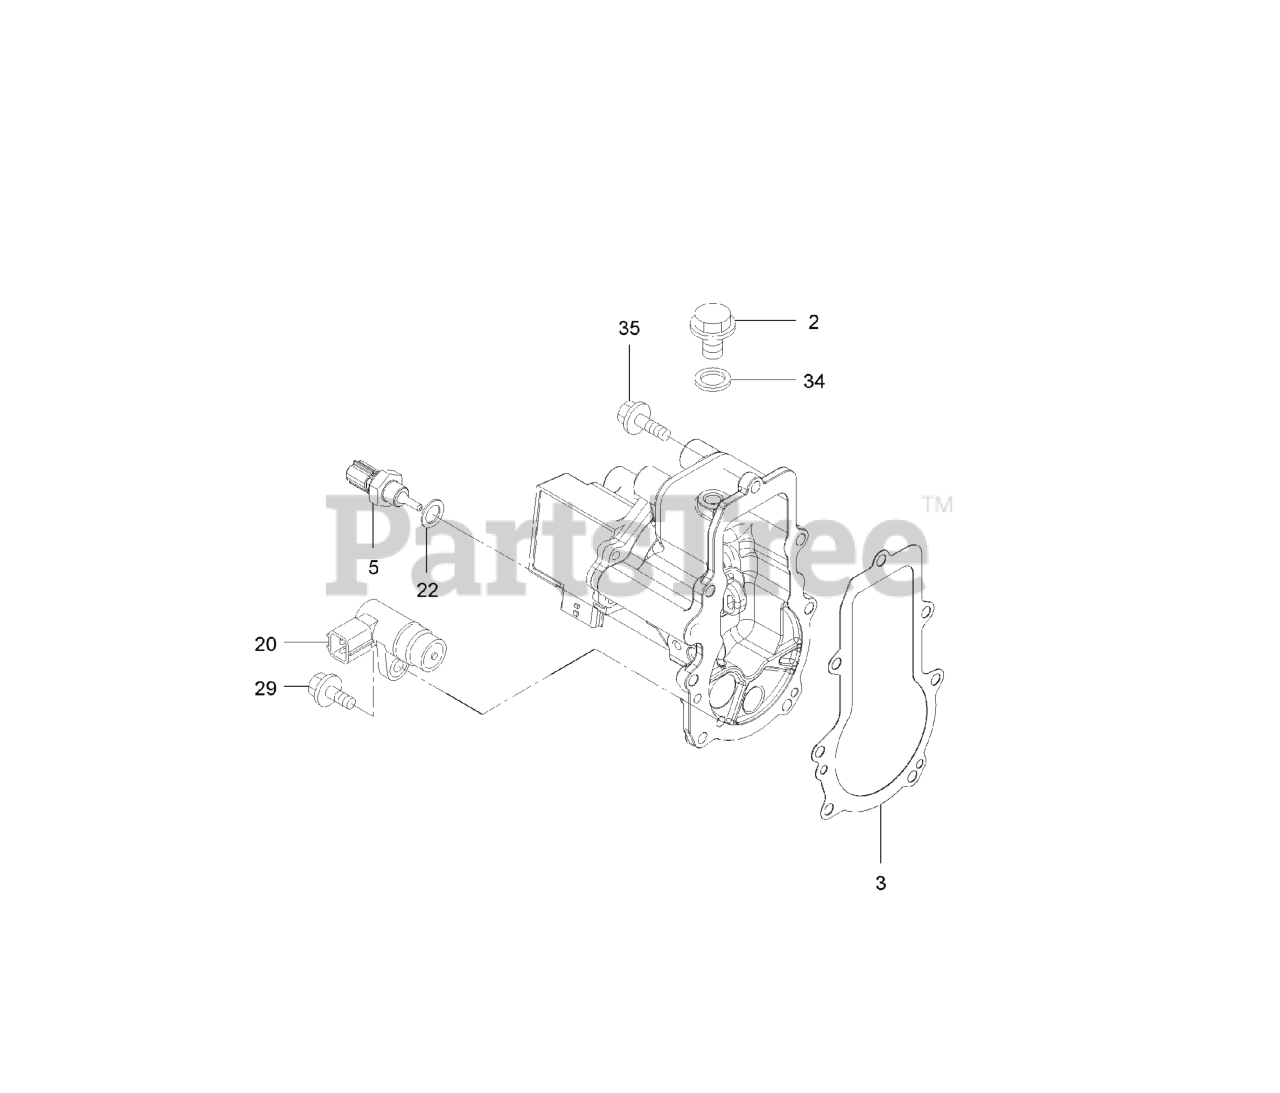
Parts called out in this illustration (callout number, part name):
5	SENSOR-OIL TEMP
22	WASHER-SEAL
34	WASHER-SEAL
